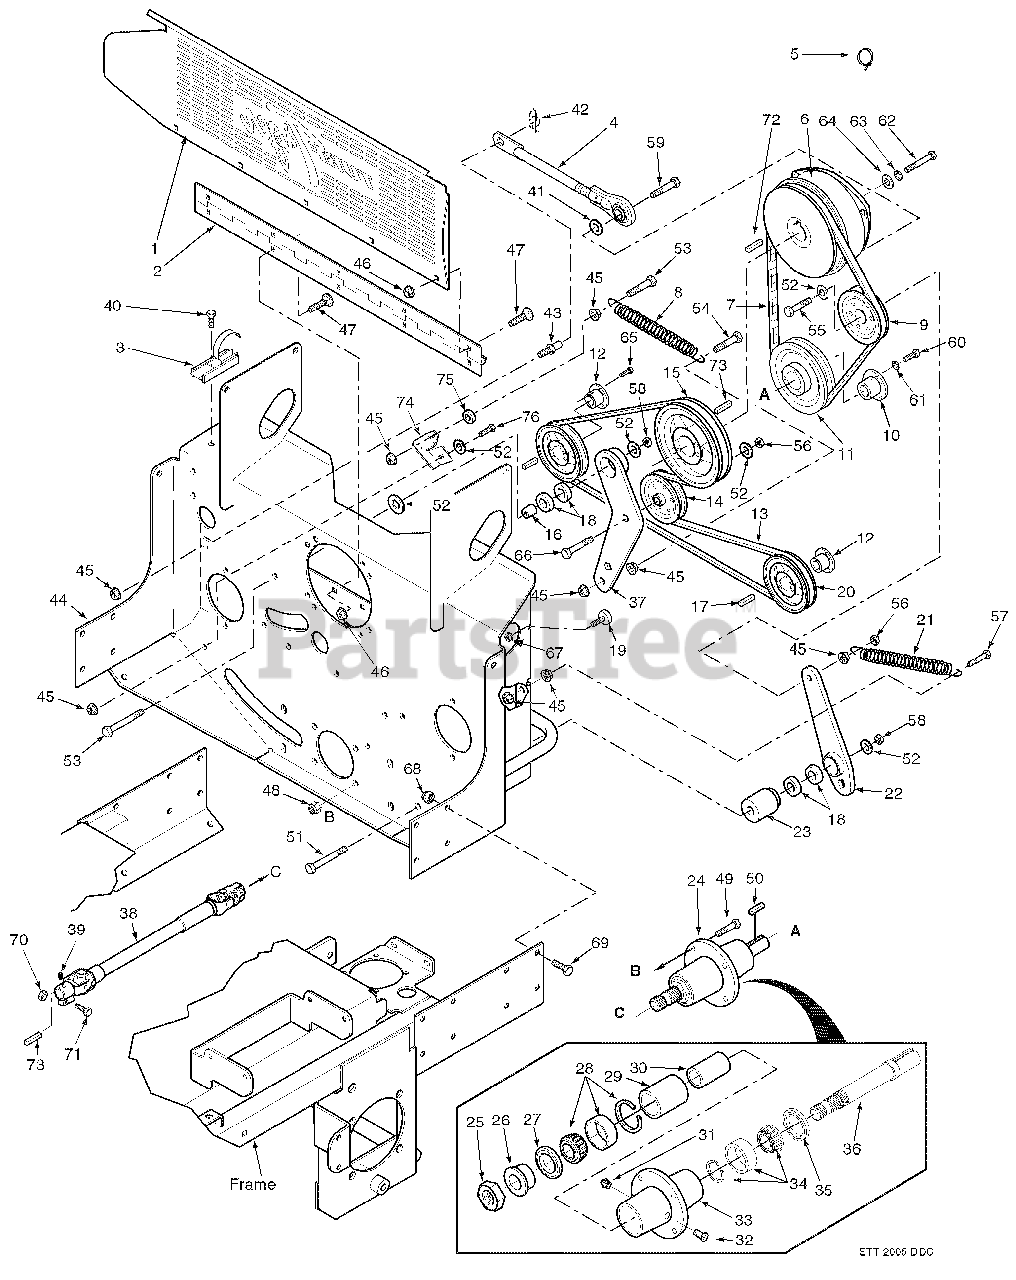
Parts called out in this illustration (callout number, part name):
1	Belt Guard, Rear
2	Hinge, Belt Guard
3	Latch, Hood
4	Rod Assembly, Clutch Anti-Rotation
5	Clamp, Cable
6	Clutch, Ogura GT-3.5
6	Clutch, Ogura GT-5
7	Belt, Deck Drive
8	Spring, Transmission Idler
9	Pulley, Idler 5" Dia.
10	Tapered Hub, 1" Bore
11	Pulley, 6.70 Tapered Bore
12	Tapered Hub, 17mm Bore
13	Belt, Pump Drive STT
13	Belt, Pump Drive
14	Pulley, Idler 4" Dia.
15	Pulley, 4.55 Dia.-1.125 Bore
15	Pulley, 5.367 Dia. - 1.125 Bore
16	Spacer, Idler Bearing
17	Key, 5.0 x 5.0 x 25mm
18	Ball Bearing
19	Bumper, Rubber
20	Pulley, 5.75" O.D.
21	Spring, PTO
22	Idler Arm Weldment, PTO Drive
23	Pivot, Idler PTO
24	Spindle Assembly, Deck Drive
25	Nut, 1.06-18 Thread
26	Spindle Bushing, Bottom
27	Seal, 2.0 OD x 1.625 Bore
28	Roller Bearing Tapered
29	Spacer, Outside
30	Spacer, Inside
31	Grease Fitting, 1/4-28
32	Relief Fitting
33	Spindle Housing
34	Roller Bearing Tapered
35	Seal, 2.0 OD x 1.5 Bore
36	Shaft, Deck Drive
37	Idler Arm Weldment, Pump Drive
38	Driveshaft
39	Set Screw, 3/8-16 x 3/4" Torx Socket
40	Screw, #10-32 x .56
41	Flatwasher, 3/8-.391 x .938 x .105
42	Pin, Rue Cotter 3/8 Dia.
43	Stud, Anti Rotation
44	Pump Mounting Plate Weldment
45	Nut, Serrated Flange 3/8-16
46	Nut, Serrated Flange 1/4-20
47	Bolt, Carriage 1/4-20 x 1/2"
48	Nut, Elastic Stop 5/16-18 Grade 8
49	Bolt, Hex Head 5/16-18 x 1-3/4" Grade 8
50	Key, 1/4 x 1/4 x 1-1/2"
51	Bolt, Hex Head 3/8-16 x 4-1/2" Grade 8 Black
52	Washer, 3/8" Hardened
53	Bolt, Hex Head 3/8-16 x 1-3/4" Grade 8 Black
54	Bolt, Hex Head 3/8-16 x 1-1/2" Grade 8 Black
55	Bolt, Hex Head 3/8-16 x 2-1/2" 1.5 Thread Grd.8
56	Nut, Center Lock 3/8-16
57	Bolt, Hex Head 3/8-16 x 1-1/2" Grade 8 Black
58	Nut, Elastic Stop 3/8-16
59	Bolt, Hex Head 3/8-16 x 2"
60	Bolt, Hex Head 1/4-20 x 1-3/8"
61	Lockwasher, 1/4" Spring
62	Bolt, Hex Head 7/16-20 x 2-1/2" UNF
63	Lockwasher, 7/16" Spring
64	Flatwasher, 7/16-.469 x 1.75 x .25
65	Bolt, Hex Head 1/4-20 x 1" Grade 8
66	Bolt, Hex Head 3/8-16 x 1-3/4"
67	Nut, Serrated Flange 5/16-18
68	Nut, Elastic Stop 3/8-16
69	Bolt, Hex Head 3/8-16 x 1"
70	Nut, Center Lock 3/8-16
71	Bolt, Hex Head 3/8-16 x 1-3/4"
72	Key, 1/4 x 1/4 x 2-1/4"
73	Key, 1/4 x 1/4 x 1"
74	Bracket
75	Spacer
76	Bolt, Hex Head 3/8-16 x 1"
